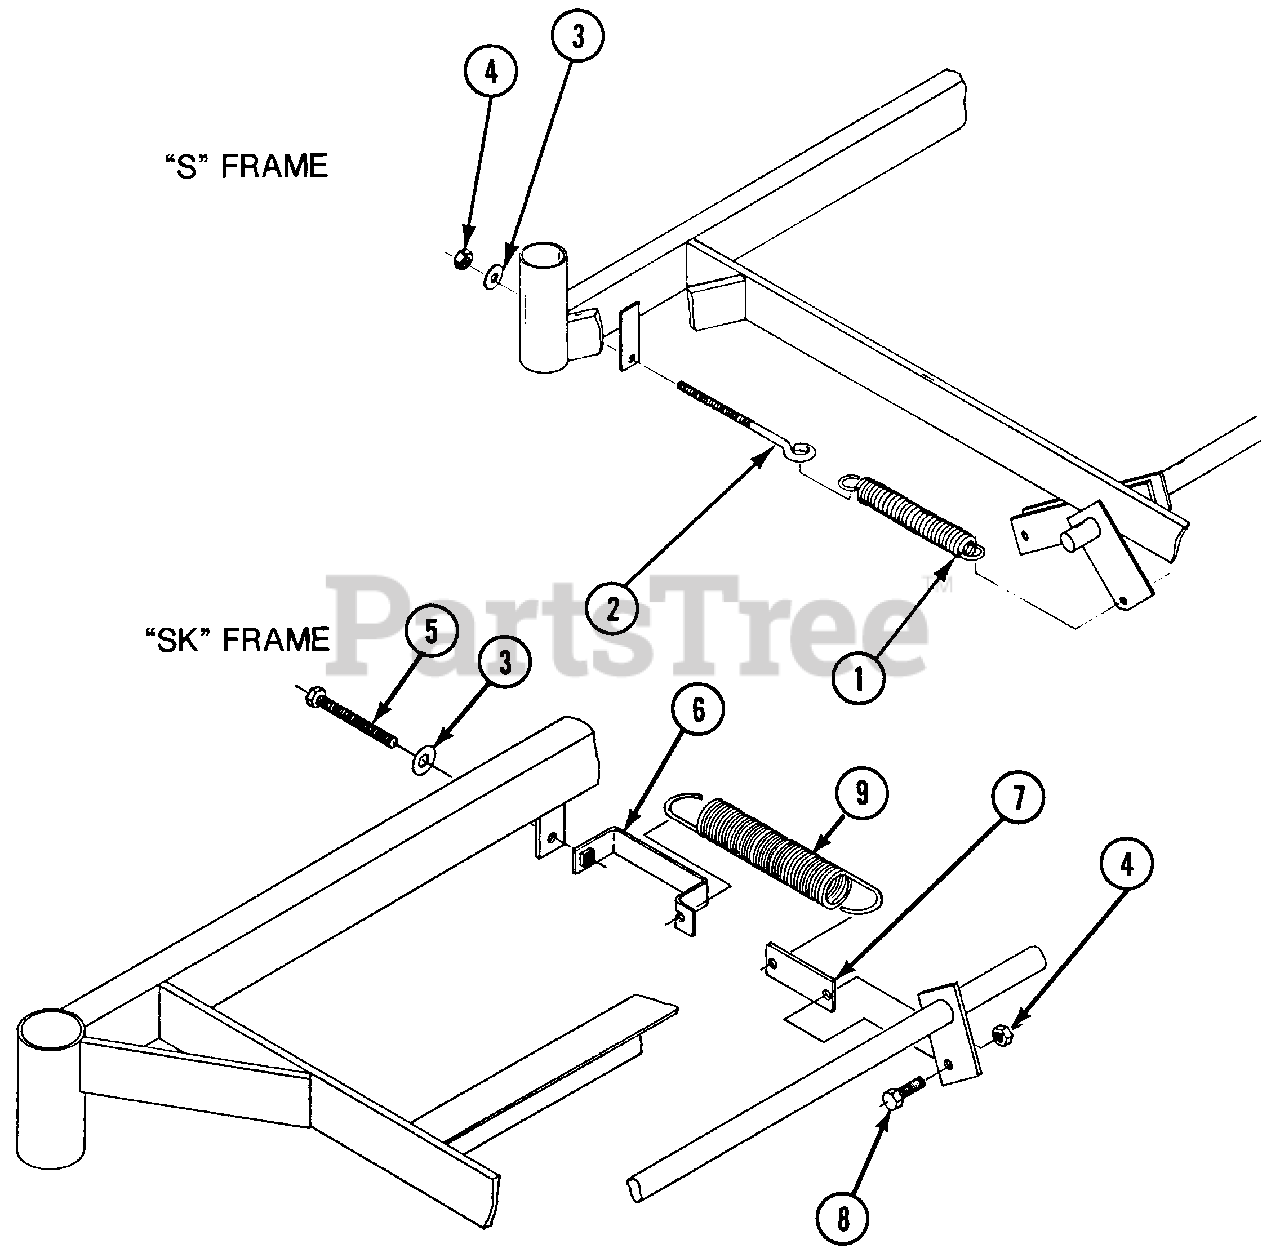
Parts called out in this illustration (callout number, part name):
1	DECK SPRING, 1-1/2" X 8" LONG
2	EYEBOLT 3/8-16 x 7-1/2" (FULL EYE)
3	WASHER, 3/8 STD, FLAT
4	LOCKNUT, HEX, 3/8-16, W/NYLOC
5	CAPSCREW, 3/8-16 X 3 ALL THRD.
6	SPRING TIGHTENER 42" & 48" DECKS
7	SPRING EXTENSION PLATE
8	CAPSCREW, 3/8-16 X 1 GR.5
9	DECK SPRINGER 1.65" X 9" LONG
